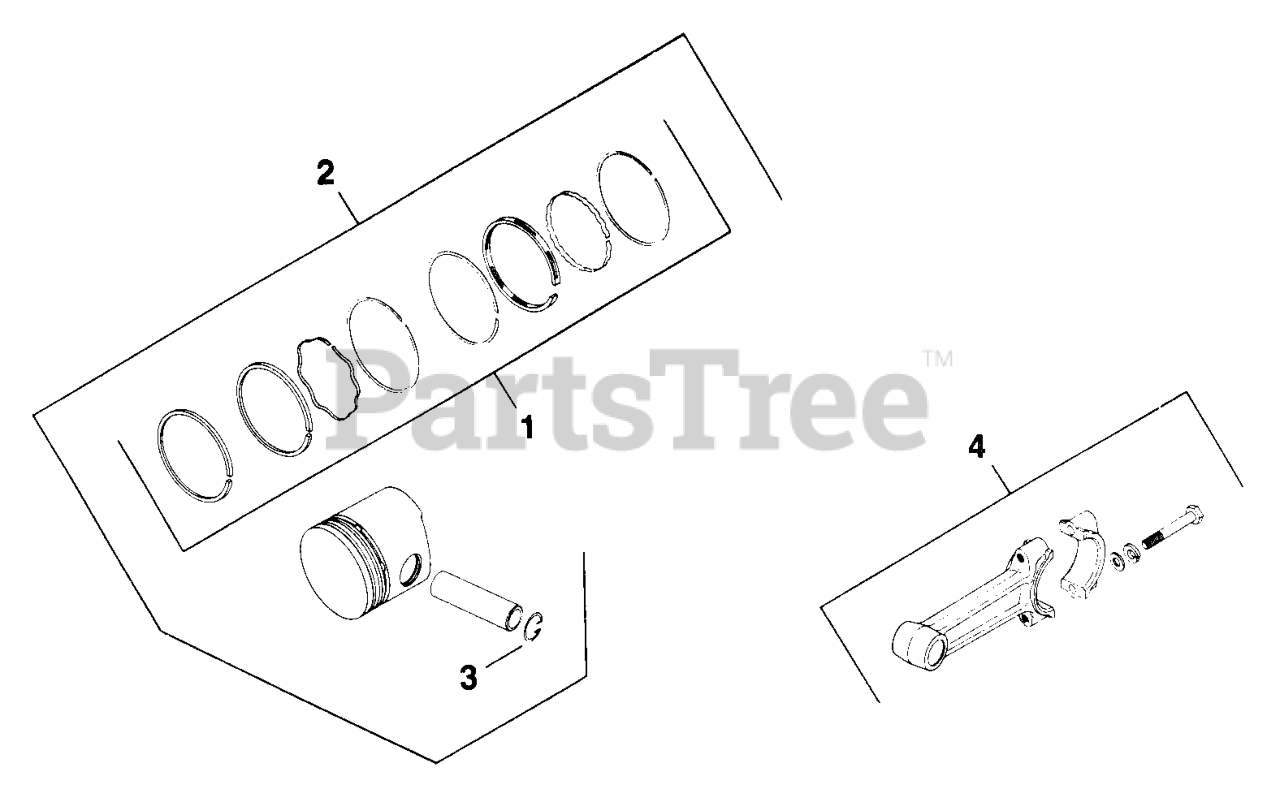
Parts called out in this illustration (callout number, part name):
1	RINGS STD. - DISCONTINUED
1	RINGS .010
1	RINGS .020
1	RINGS .030
2	KIT, PISTON W/RING SET STD
2	PISTON W/RING SET .003
2	KIT, PISTON W/RING SET .010-(#DSC)
2	KIT, PISTON W/RING SET .020
2	PISTON W/RING SET .030
3	RETAINER
4	ROD STD. - DISCONTINUED
4	ROD .010 - DISCONTINUED
